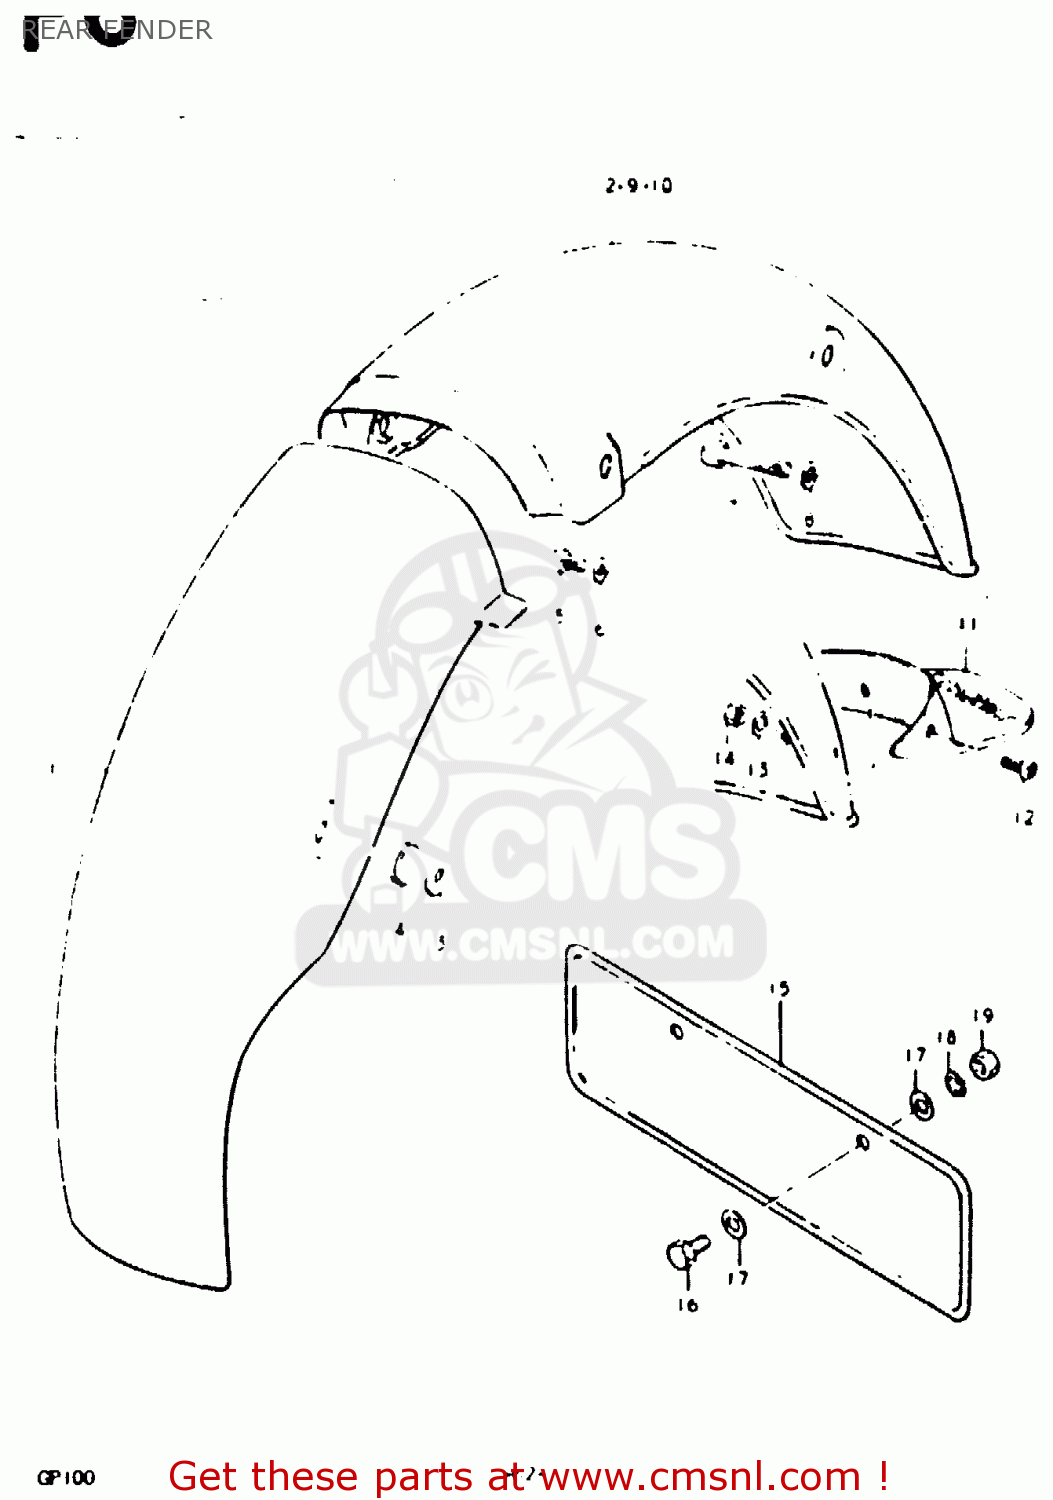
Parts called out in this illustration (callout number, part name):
1	BODY, REAR FENDER FRONT
2	BODY, REAR FENDER REAR
3	WASHER
4	CUSHION
5	BOLT
6	LOCK WASHER
7	BOLT
8	LOCK WASHER
